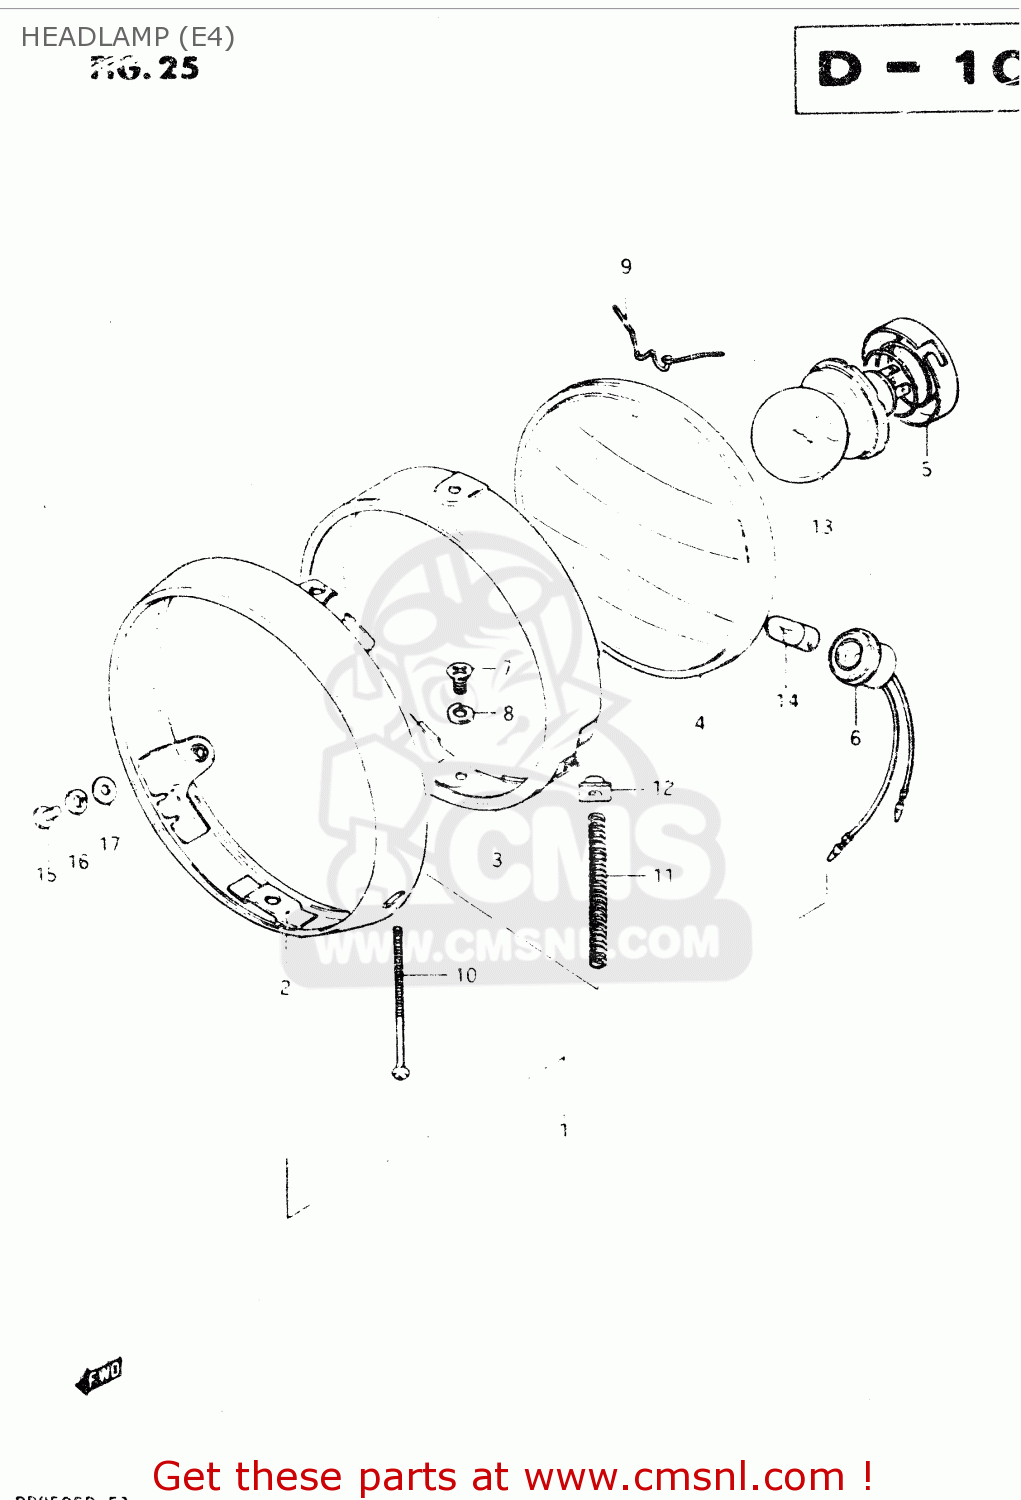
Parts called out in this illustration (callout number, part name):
1	HEADLAMP ASSY
2	RIM,HEADLAMP
3	RETAINER
4	UNIT
5	SETTER,BULB
6	SOCKET
7	SCREW
8	LOCK WASHER
9	SPRING
10	SCREW
11	SPRING
12	NUT
13	BULB (12V, 45/40W)
14	BULB(12V4W)
15	SCREW
16	LOCK WASHER
17	WASHER
